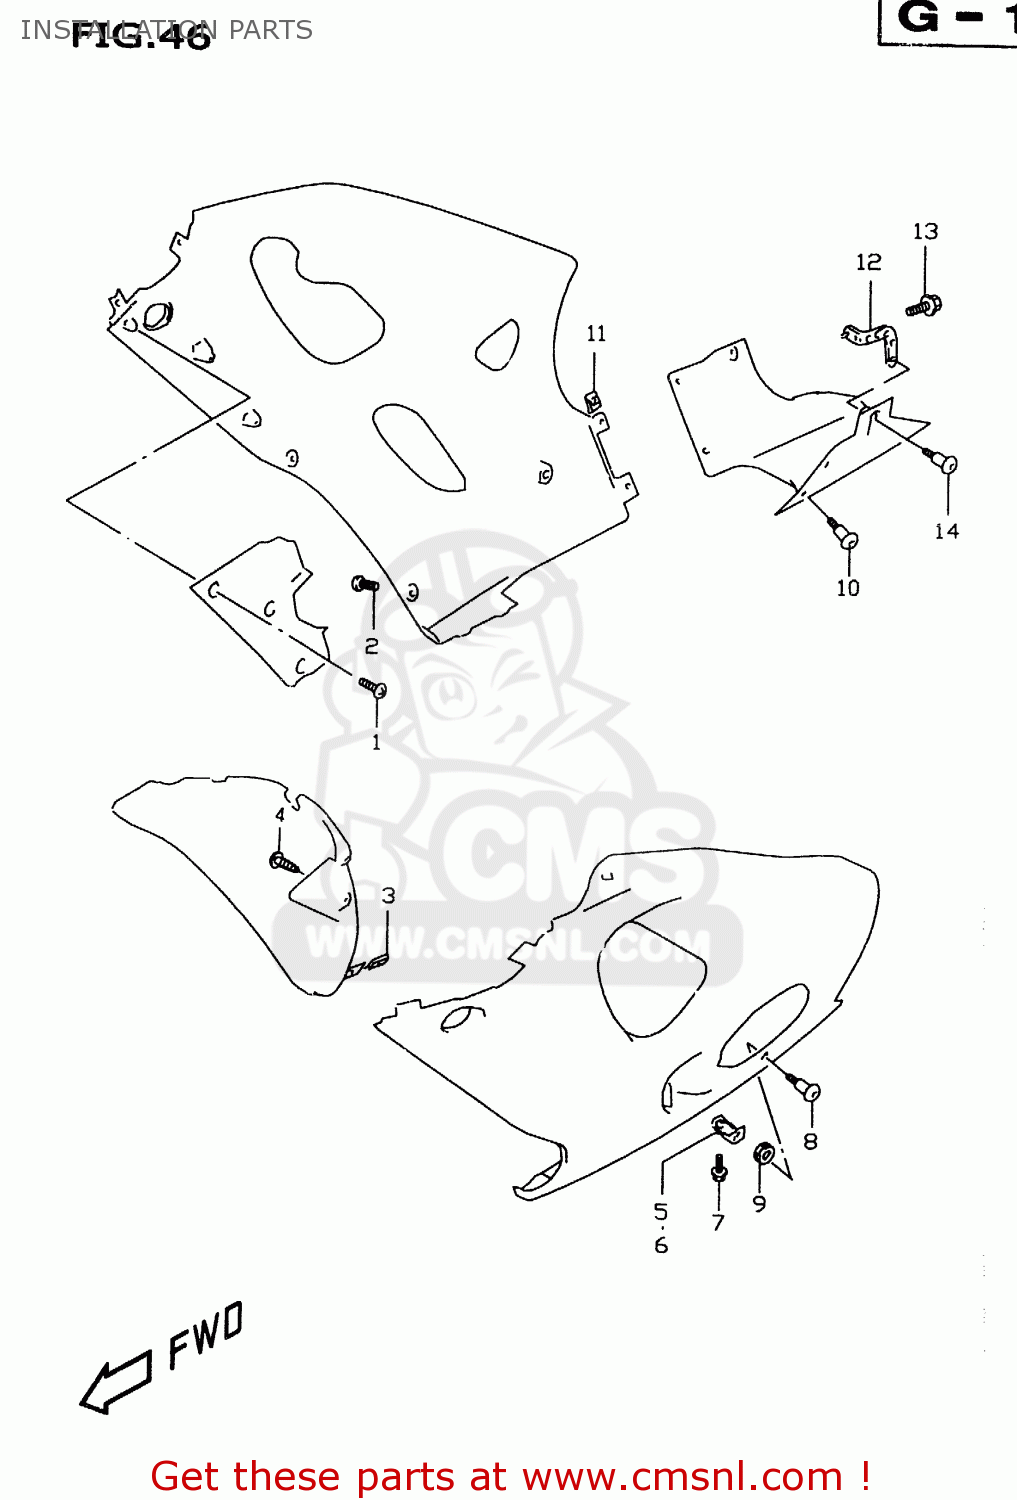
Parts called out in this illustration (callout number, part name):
1	SCREW
2	SCREW(5X16)
3	NUT,HEADLAMP HOUSING,UPPER
4	SCREW
5	BRACKET,UNDER COWLING,LOWER
6	BRACKET,UNDER COWLING,LOWER
7	BOLT
8	SCREW(6X20)
9	CUSHION
10	SCREW(5X16)
11	NUT,HEADLAMP HOUSING,UPPER
12	BRACKET,RR UNDER COWLING
13	BOLT
14	SCREW(5X16)
